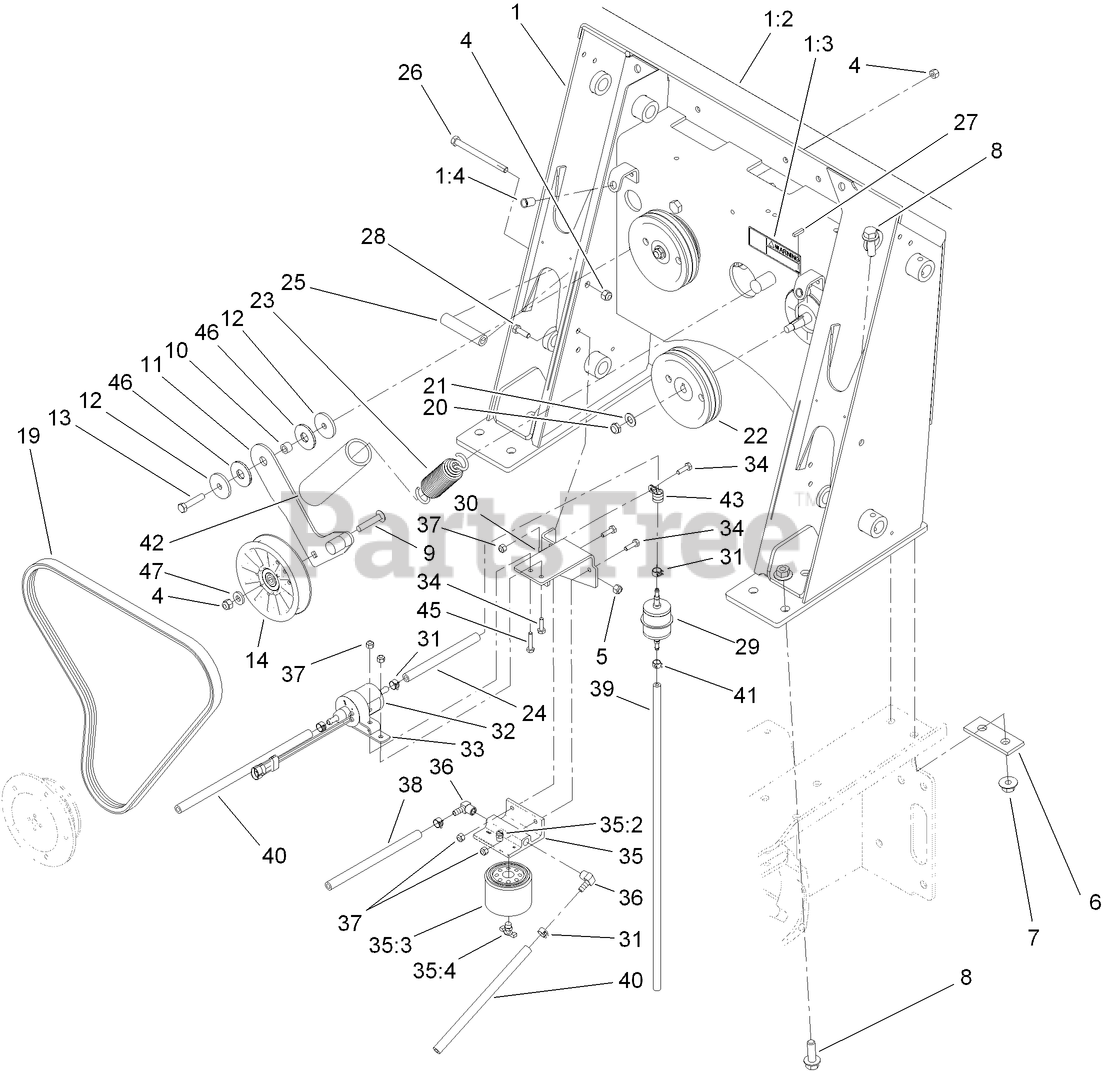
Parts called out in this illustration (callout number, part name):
1	LOADER TOWER ASM
1:2	DECAL-PANEL, CONTROL
1:3	DECAL-DANGER
1:4	INSERT-THREADED
4	NUT-HF, NI
5	NUT-LOCK, NI
6	PLATE-STIFFENER
7	NUT-LOCK, FLANGE
8	SCREW-HHF
9	BOLT-CARRIAGE
10	SPACER
11	IDLER ARM ASM
12	WASHER-PLAIN
13	SCREW-HH
14	PULLEY-IDLER
19	V-BELT
20	NUT-LOCK, NI
21	WASHER-FLAT
22	PULLEY-3V
23	SPRING-EXTENSION
24	HOSE-FUEL
25	TUBE-SPACER
26	SCREW-HH
28	SCREW-HH
29	FILTER-INLINE
30	BRACKET-PUMP, FUEL
31	CLAMP-HOSE
32	PUMP-FUEL
33	BRACKET-PUMP, FUEL
34	SCREW-HH
35	FILTER HEAD ASM
35:2	VENT-AIR
35:3	FILTER-SEPARATOR, WATER
35:4	VALVE-DRAIN
36	FITTING-ELBOW
37	NUT-LOCK, NI
38	HOSE-FUEL
39	HOSE-FUEL
40	HOSE-FUEL
41	CLAMP-HOSE
42	RETAINER-SPRING
43	CLAMP-R
45	SCREW-HH
46	WASHER-FRICTION, COMPOSITE
47	SPACER
